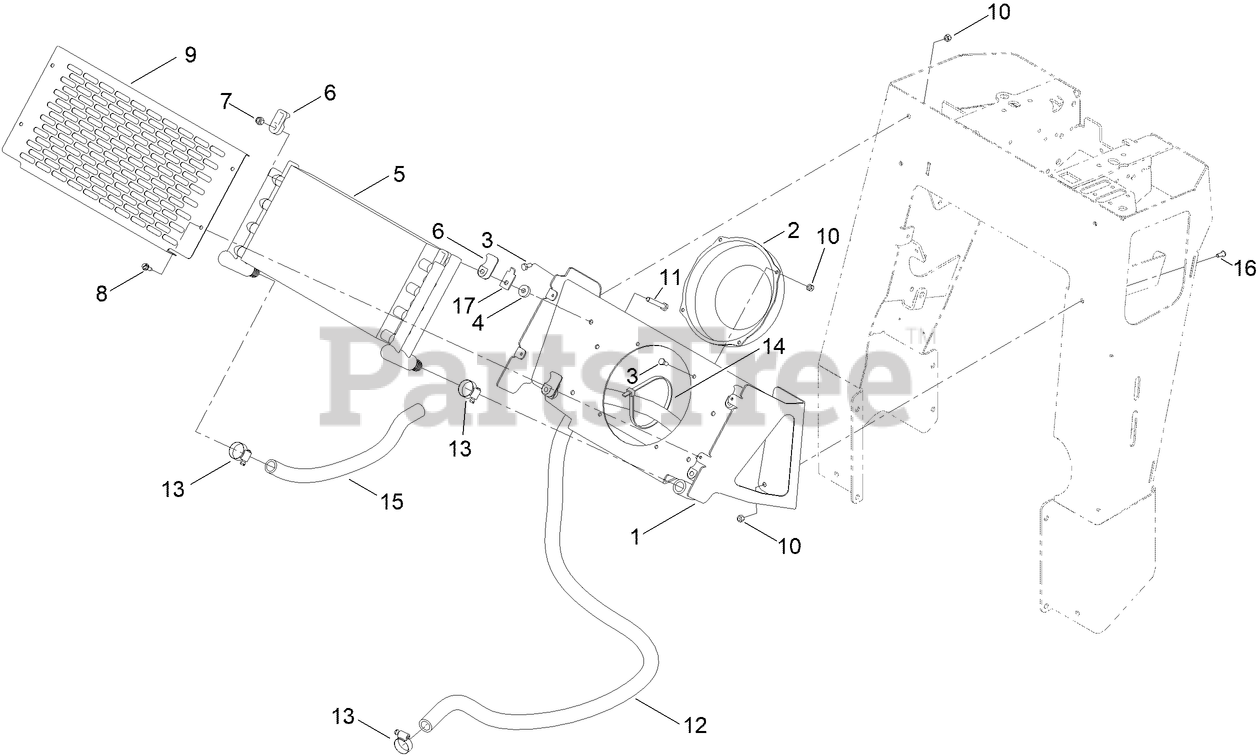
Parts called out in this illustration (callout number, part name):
1	MOUNT-COOLER
3	SCREW-HH
5	COOLER-OIL
7	NUT-LOCK, NI
8	SCREW-HWH
9	COVER-COOLER
10	NUT-LOCK, NI
11	SCREW-HH
12	HOSE-RETURN
13	CLAMP-HOSE
14	TIE-CABLE
15	HOSE-RETURN
16	SCREW-HSBH
17	PLATE-SUPPORT, CLAMP
